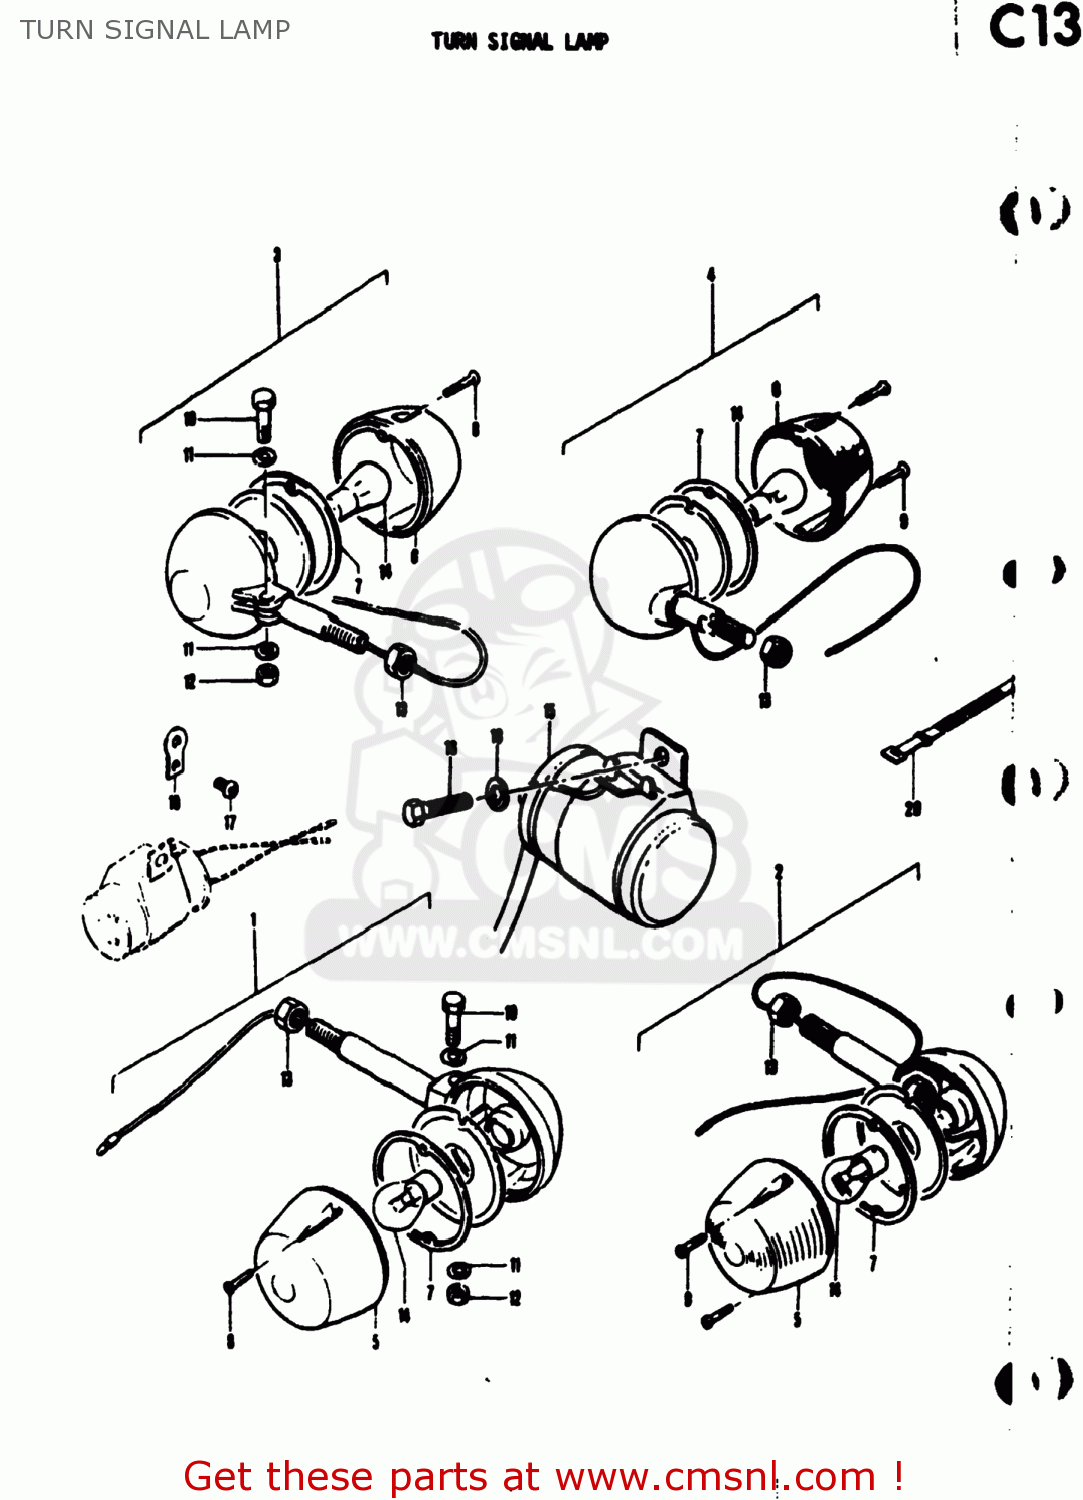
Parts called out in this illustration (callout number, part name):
1	LAMP ASSEMBLY,FRONT TURN SIGNAL
2	LAMP ASSY,FR TURN SIGNAL
3	LAMP ASSEMBLY,REAR TURN SIGNAL
4	LAMP ASSEMBLY,REAR TURN SIGNAL
5	LENS,TURNSIGNAL
6	LENS,RR TURNSIGNAL LAMP
7	GASKET,TURNSIGNAL LENS (NAS)
8	SCREW
9	SCREW
10	BOLT,HOUSING
11	WASHER 6MM
12	NUT
13	NUT
14	BULB(6V17W,STANLEY,A4513A)
15	RELAY,TURN SIGNAL
16	BOLT
17	SCREW,6X6
18	LOCK WASHER
20	CLAMP
